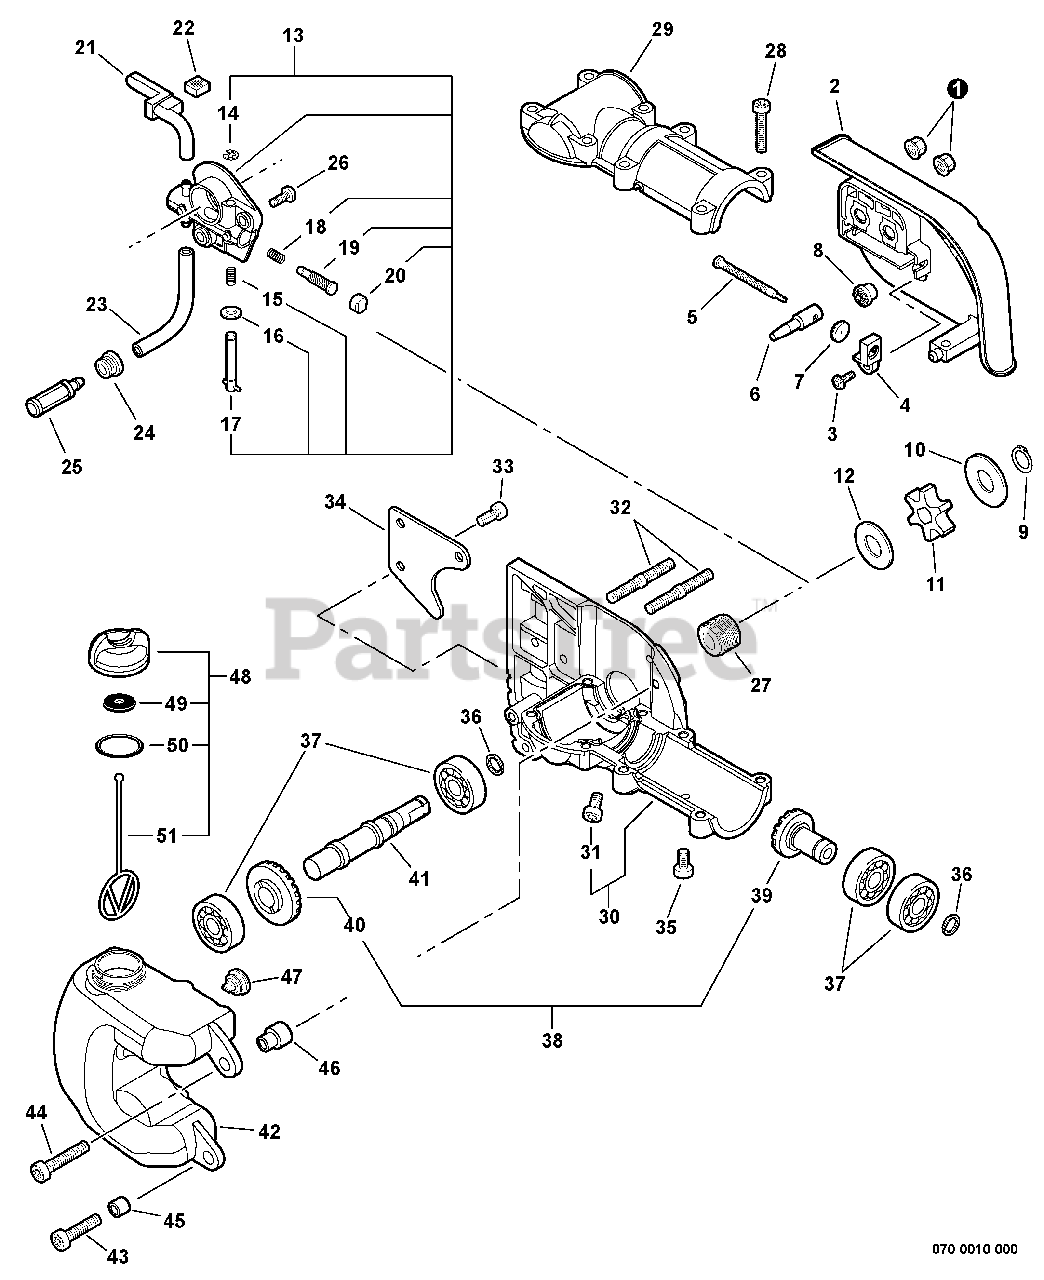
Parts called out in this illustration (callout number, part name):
1	NUT - 6 -- FLANGE
2	GUARD, SPROCKET
3	SCREW - 4X8
4	BRACKET, TENSIONER
5	SCREW, TENSIONER
6	TENSIONER, CHAIN
7	GEAR - BEVEL
8	GEAR - BEVEL
9	RING, RETAINING
10	WASHER - 10
11	SPROCKET, DRIVE
13	AUTO-OILER ASSY
14	RING, RETAINING
17	NEEDLE, ADJUST
19	PLUNGER
20	CAP, OIL PUMP
21	PIPE, OIL OUTLET
22	PAD, FOAM
23	PIPE - 3X6X75 -- BLACK
24	GROMMET
25	FILTER, OIL
26	SCREW - 5X10
27	GEAR - WORM
28	SCREW - 5X25
29	CASE, GEAR - UPPER
30	CASE, GEAR - LOWER
31	SCREW - 5X10
32	STUD, GUIDE BAR
33	SCREW - 5X10
35	SCREW - 5X10
36	RING, RETAINING - 12
37	BEARING, BALL - 6001
38	GEAR SET
39	GEAR - BEVEL
40	GEAR - BEVEL
41	GEAR - SHAFT
42	TANK, OIL
43	SCREW - 5X20
44	SCREW - 5X25
48	CAP ASSY - ORANGE
49	WASHER - RUBBER
50	O-RING - 18
51	CONNECTOR, CAP
